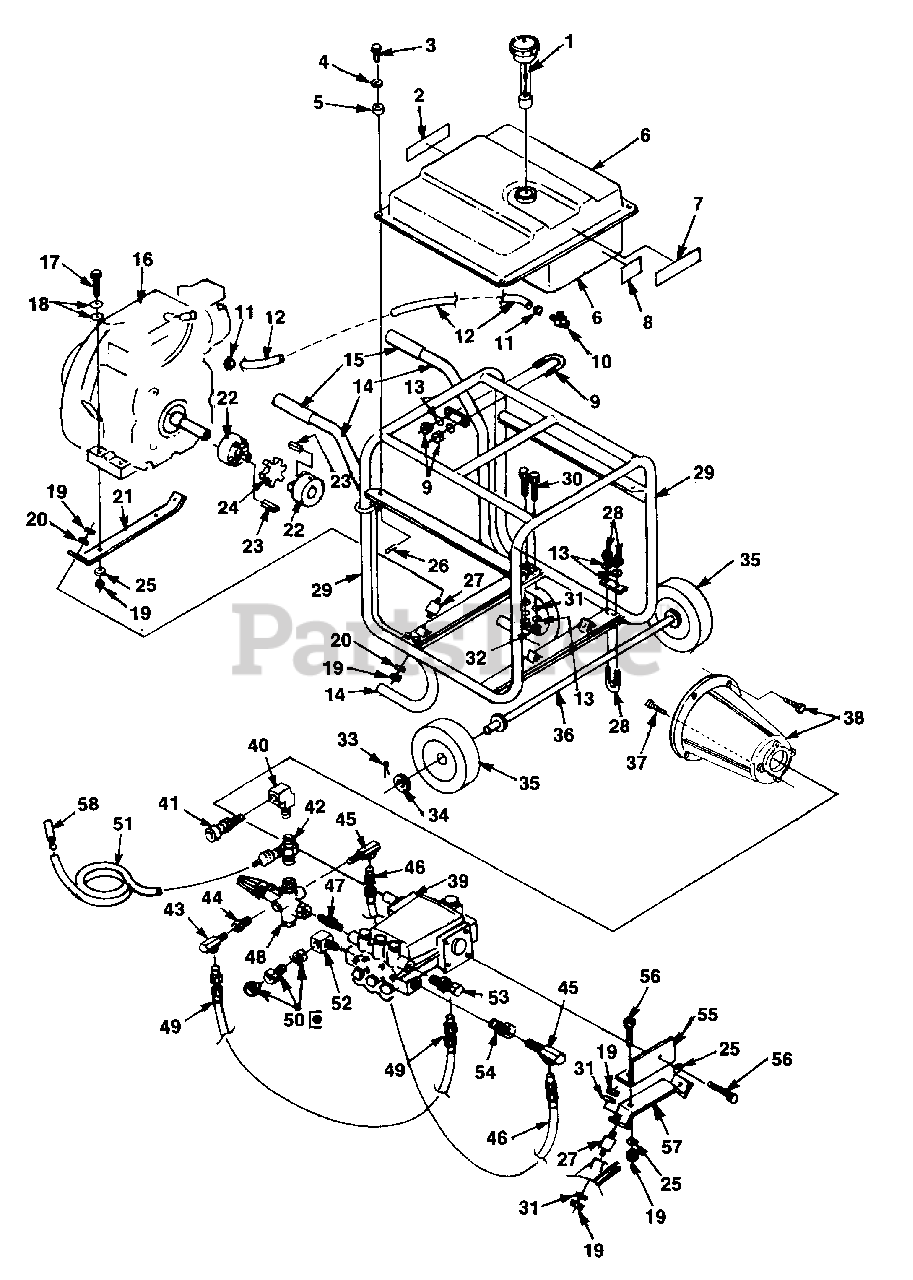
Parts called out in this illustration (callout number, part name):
3	PIN TBO
4	FLAT WASHER TBO
5	GROMMET-Isolator
6	FUEL TANK
7	OPER DECAL
8	DECAL, 172R24
10	VALVE- Fuel
11	Clip - Hose
13	WASHER, LOCK
14	Tubing, Handle
15	Grip, Handle
17	SCREW - HEX CAP (5/16-18 x 1 1/2)
18	FLAT WASHER(HSD'S) TBO
20	Washer - Lock (int.)
21	SUPPORT-Engine
23	KEY SQUARE 1/4 IN TBO
24	COUPLING SPIDER TBO
25	3WASHER(HPW1200B) TBO
26	PIN TBO
27	VIBRATION ISOLATOR
28	Superseded by UP05656
30	SCREW, CAP HEX HD
32	NUT-(1/4-20)
33	COTTER PIN (RDP3) TBO
34	WASHER, FLAT (RDP3) TBO
40	3/8 NPT STREET ELBOW
41	FEMALE SOCKE TBO
44	BUSHING
45	STREET ELBOW
48	UNLOADERS (HPW2000B TBO
50	SPRING & ADAPTOR
52	STREET ELBOW
56	BOLT- (5/16-18 x 3/4")
57	SUPPORT-Generator
58	STRAINER
